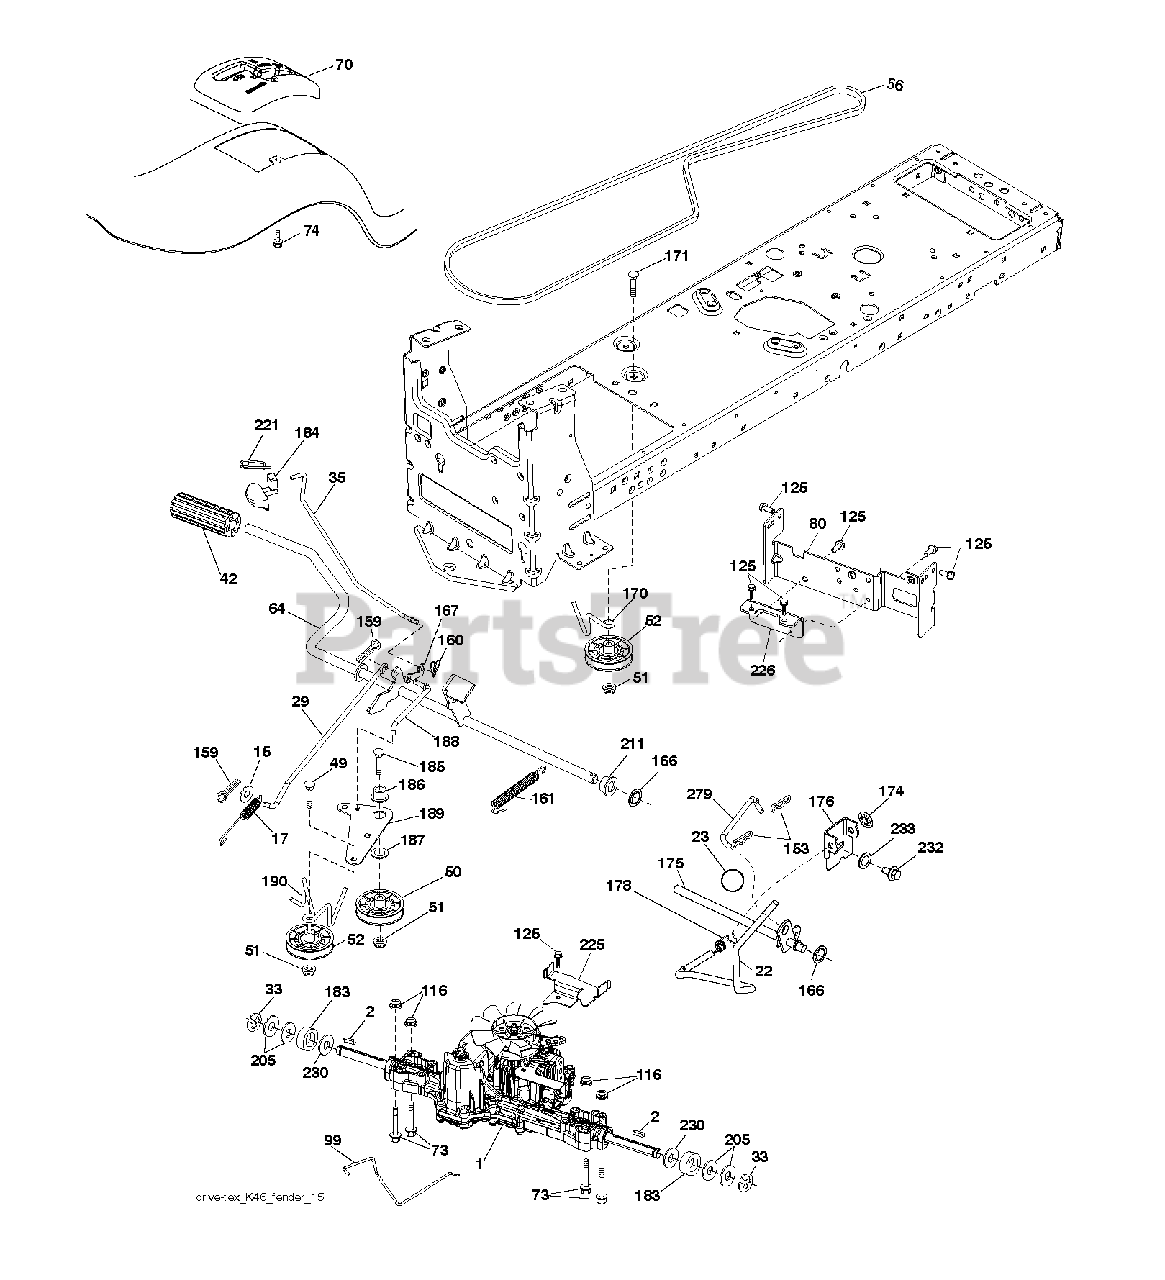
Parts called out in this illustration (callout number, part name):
2	SQUARE KEY
17	SPRING.BRAKE.K46.GREEN
22	ROD.SHIFT.FENDER.TLT.2006
29	ROD.BRAKE.K46
33	E-RING LT
35	ROD.BRAKE.PARKING.LT.T
49	BOLT
50	IDLER.FLAT.910.OFFSET
51	NUT LOCK FLG 3/8-16 UNC
52	IDLER.V-GROOVE.910.OFFSET
56	V-BELT.MOWER.92.40.42/K46
64	SHAFT.ASM.PEDAL.BRAKE.
70	CONSOLE.SHIFT.STL.HYD.BLACK
73	BOLT HEX 5/16-18 GR 5
74	SCREW.HI-LO.CONSOLE
80	STRAP TORQUE.ASM.K46/18"TEX
99	ROD.SPRING.BYPASS.K46.LT.Z
116	NUT LOCK HEX FLANGE 5/16-18
125	SCREW
159	COTTER PIN
160	RETAINER CLIP
161	SPRING, RETURN LT
166	NUT.PUSH.625.2006
167	LATCH.BRAKE.SPRING
170	KEEPER.V-IDLER.CENTER.
171	BOLT
174	NUT.PUSH.500.2006
175	SHAFT ASM SHIFT
176	ARM.CLEVIS.ROD.SHIFT
178	SPRING.SHIFT.GT2006
183	SPACER AXLE
186	SPACER.RETAINER
187	WASHER 12/32X2X10GA
188	LINK.CLUTCH.GROUND.DRIVE
189	BELLCRANK.GROUND.DRIVE.TEX.
190	KEEPER.BELLCRANK.DRIVE
211	BUSHING.SHAFT.BRAKE.HAND
221	RETAINER.SPRING.CLIP.H
225	KEEPER.BELT.TRANSAXLE.K46
226	BRACKET.MOUNT.TORQUE.K46.TLT
230	WASHER.HARDENED
232	BOLT FIN HEX 7/16-14 X 1
233	WASHER SERRATED
279	LINK.SHIFT.T/A.K46.FEND.TX
